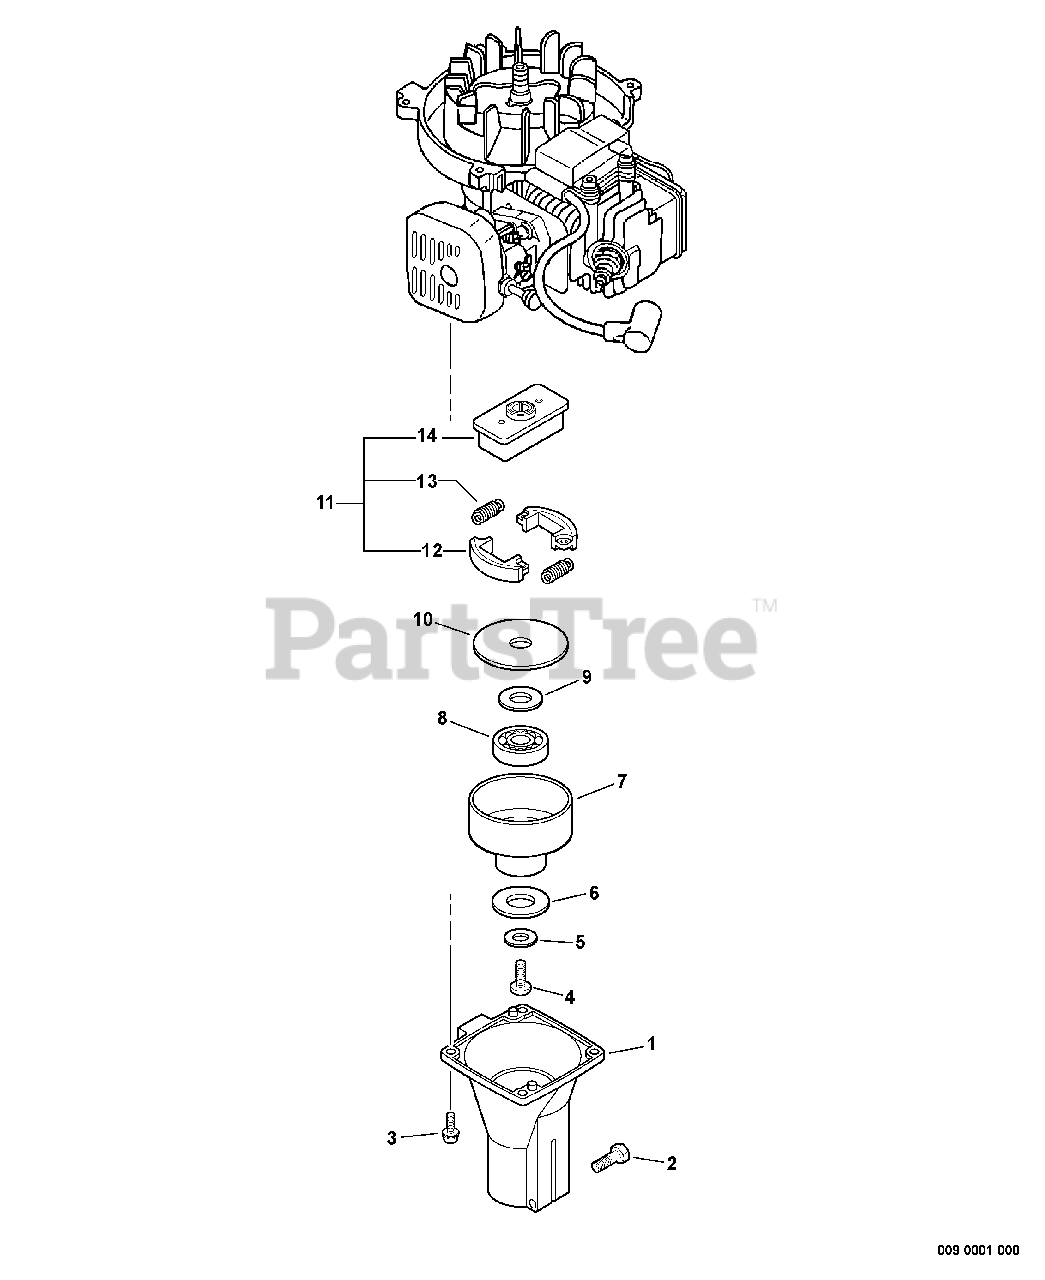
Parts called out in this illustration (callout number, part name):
1	CASE, CLUTCH
2	BOLT - 5X25
3	SCREW - 4X14
4	SCREW - 6X12
5	WASHER, CLUTCH
6	WASHER, CLUTCH
7	DRUM, CLUTCH
8	BEARING, BALL - 6000
9	WASHER - 10
10	PLATE, CLUTCH
11	CLUTCH ASSY
12	SHOE, CLUTCH
13	SPRING, CLUTCH
14	HUB, CLUTCH
